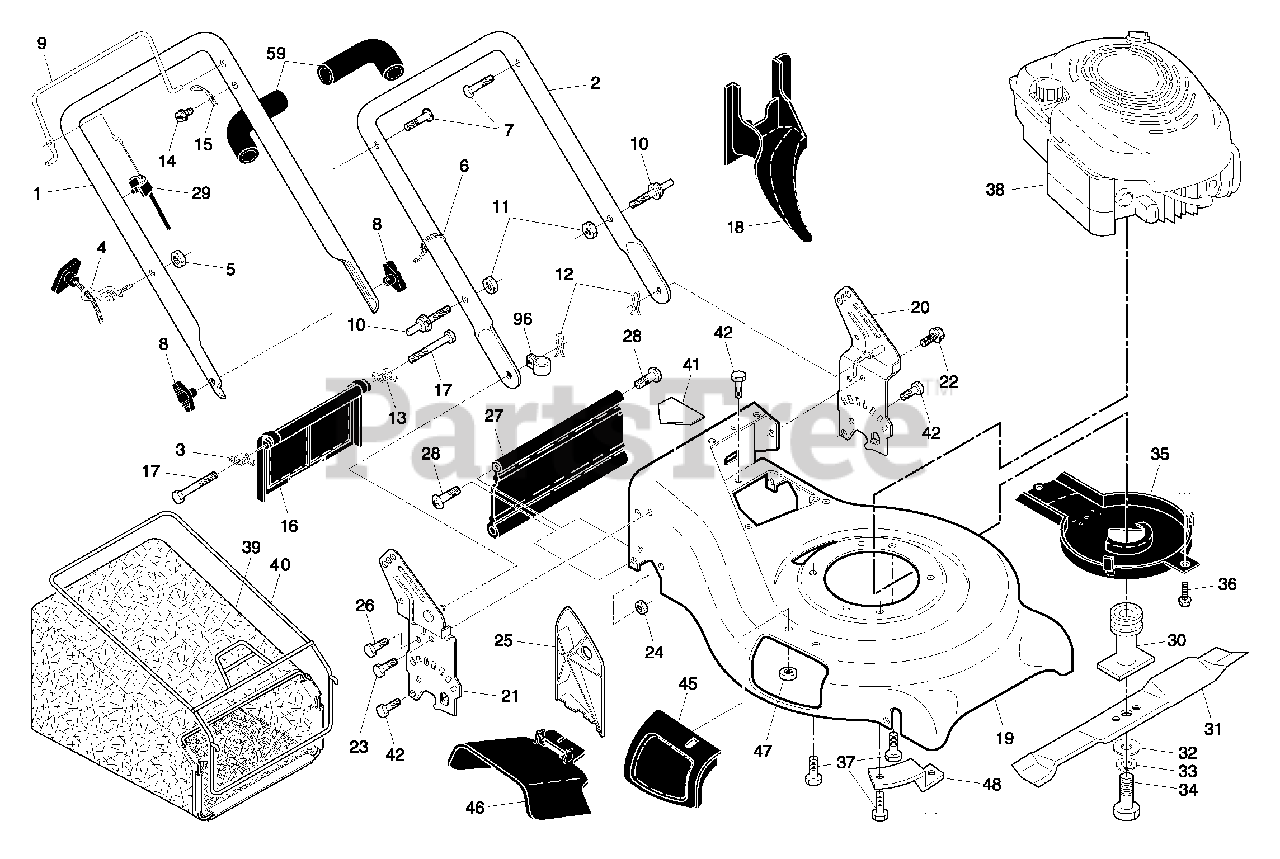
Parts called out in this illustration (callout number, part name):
1	Handle, Upper
2	Handle, Lower
3	Spring, Rear Door, RH
4	Guide, Rope, Side
5	Nut, Hex Lockwasher Insert 1/4-20
6	Wire, Tie
7	Bolt, Handle 5/16-18 x 1.75
8	Knob, Handle
9	Bail, Flat, Auto-Walk, Orange
10	Bolt, Carriage
11	Nut, Hex, Centerlock 5/16-18 UNC
12	Cotter, Hairpin
13	Spring, Rear Door, LH
15	Bracket, Upstop
16	Rear Door Assembly
17	Bolt, Rear Door
18	Plug, Mulcher
19	Kit, Housing
20	Handle Bracket Assembly, LH
21	Handle Bracket Assembly, RH
22	Screw, Hex Washer Head
23	Bolt, Hex Head 5/16-18 x 5/8
24	Nut, Hex, with Lock Washer Insert 5/16-18
25	Baffle, Side
26	Screw, Hi-Lo Thread #12 x 5/8
27	Skirt, Rear
28	Screw, Hinge 1/4-20 x 1.25
29	Cable, Operator Presence
30	Blade Adapter / Pulley
31	Blade, 21"
32	Washer, Hardened
33	Lockwasher, Helical Spring 3/8
34	Screw, Hex Head 3/8-24 x 1.38
35	Debris Shield
37	Bolt, Engine
39	Grassbag
40	Frame, Grassbag
41	Danger Decal
45	Mulcher Door Assembly
46	Deflector, Discharge
48	Mounting Bracket, Debris Shield
59	Grip, Handle, Foam, Smooth
96	Clip, Cable
